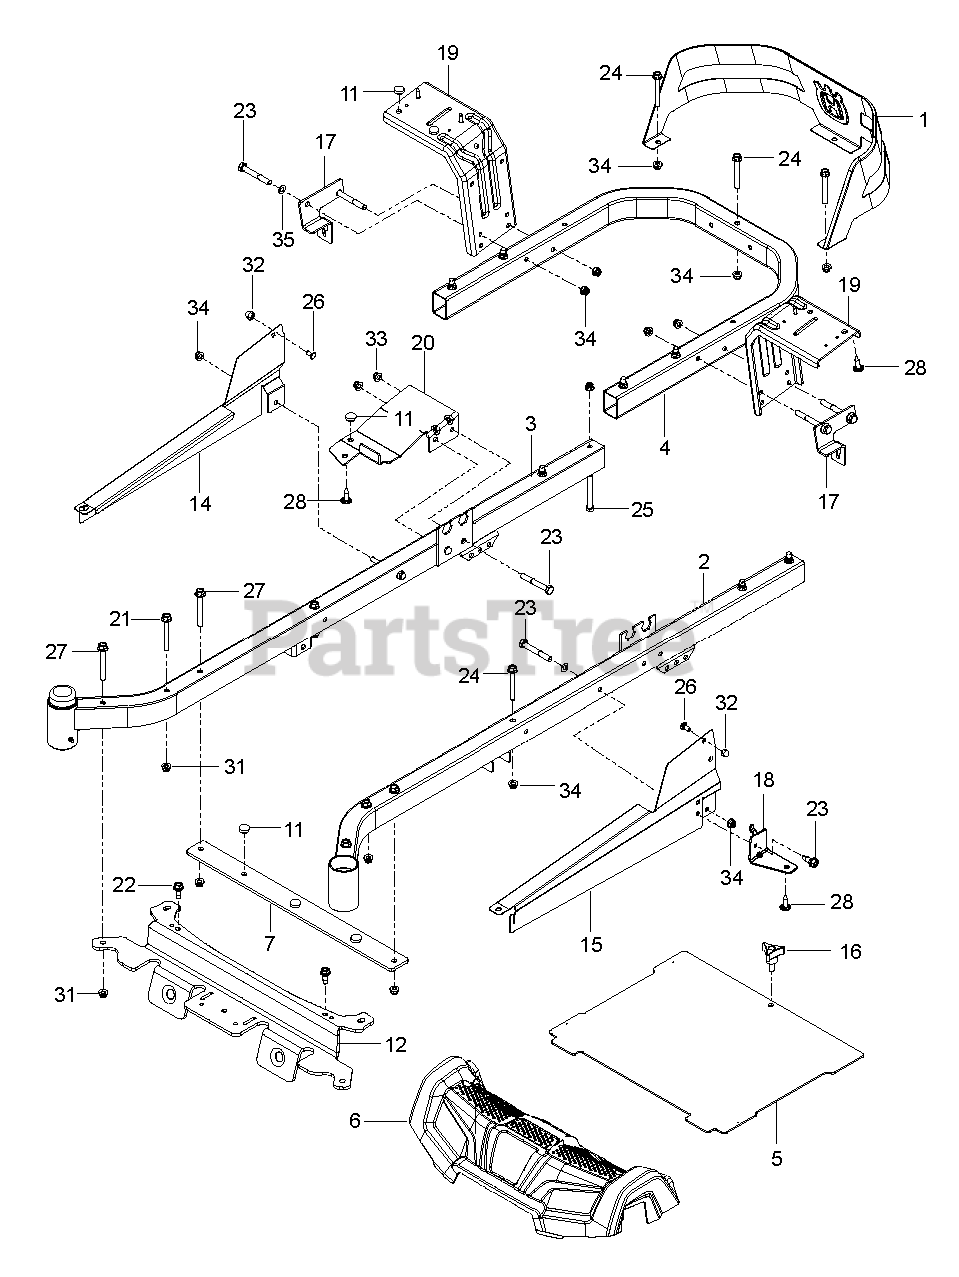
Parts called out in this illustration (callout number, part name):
1	GUARD.ENGINE.HUSQ.RZ.X498
2	FRAME.TUBE.RZ.MAIN.WELD.RH.ORG
3	FRAME.TUBE.RZ.MAIN.WELD.LH.ORG
4	TUBE.PNT.FRAME.RER.HUSQ.23".RZ
5	PLATE FOOT ORANGE X668
6	COVER.FOOTREST.REFRESH.ASM
7	FOOTREST.PLATE.SUPPORT.X431
11	GROMMET.BUMPER
12	CROSS.PNT.MEMBER.BLK
14	COVER.RAIL.RH.RZ.X668
15	COVER.RAIL.LH.RZ.X668
16	KNOB W/STUD
17	BRKT ROD.BYPASS.EZT.X431
18	SUPPORT.PNT.LH.CONSOLE.FRONT
19	FENDER.SUPPORT.PNT.X431
20	SUPPORT.PNT.RH.CONSOLE.FRONT
21	BOLT SHOULDER,FLANGED,3/8-16X3
22	BOLT.5/16-18.THRD.ROLL.SHOULDR
23	BOLT.FIN HEX 5/16-18UNC X2 1/4
25	BOLT.HEX.FIN.3/8-16 X 3.GR5
26	BOLT.CARRIAGE.5/16-18.7/16
27	HHFS 3/8-16 X 3 GRD 5 ZD
28	SCREW.#10 X 0.750.BOS
31	NUT 3/8-16 HEX FLG NYLOC ZD
32	NUT ACORN,FLANGED,5/16-18
33	NUT LOCK HEX FLANGE 5/16-18
34	5/16-18 NYLOC FLANGE NUT
35	WASHER
